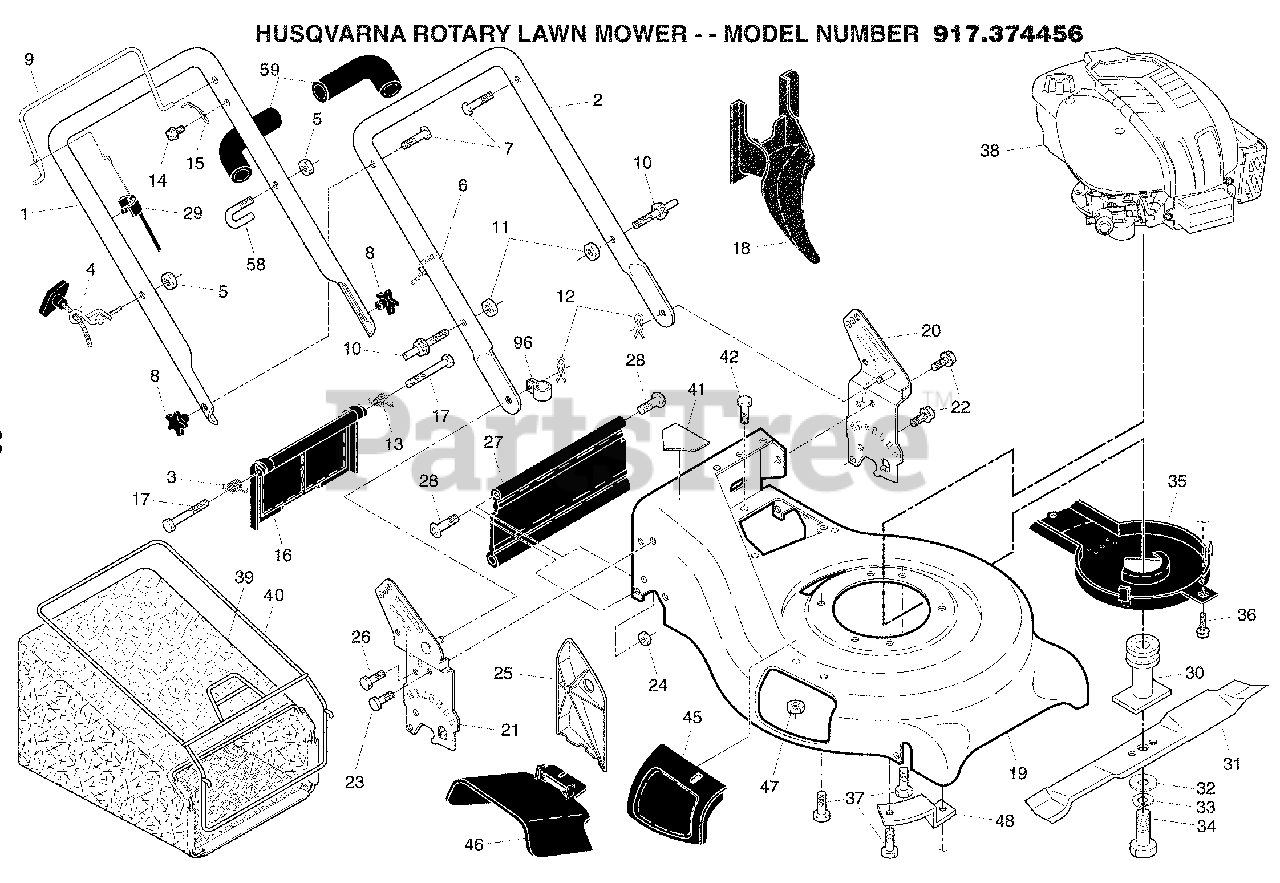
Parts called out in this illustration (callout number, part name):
1	Upper Handle Assembly
2	Handle, Lower
3	Spring, Rear Door, RH
4	Rope Guide
5	Nut, Hex, with Lockwasher Insert 1/4-20
6	Wire, Tie
7	Bolt, Handle 5/16-18 x 2-5/8
8	Knob, Handle
9	Control Bar
10	Pin, Handle Adjustment
11	Nut, Hex
12	Cotter, Hairpin
13	Spring, Rear Door, LH
14	Screw
15	Bracket, Upstop
16	Rear Door Assembly
17	Bolt, Rear Door
18	Plug, Mulcher
19	Kit, Housing
20	Handle Bracket Asembly, LH
21	Handle Bracket Assembly, RH
22	Screw, Hex Washer Head
23	Bolt, Hex Head 5/16-18 x 5/8
24	Nut, Hex, with Lockwasher Insert 5/16-18
25	Baffl e, Side
26	Screw, Hi-Lo Thread #12 x 5/8
27	Skirt, Rear
28	Screw, Hinge 1/4-20 x 1.25
29	Cable, Operator Presence
30	Blade Adapter / Pulley
31	Blade, 21"
32	Washer
33	Washer, Lock
34	Bolt, Hex Head
35	Debris Shield
36	Bolt
37	Bolt, Engine
39	Grassbag
40	Frame, Grassbag
41	Danger Decal
42	Screw
45	Mulcher Door Assembly
46	Discharge Guard
47	Nut, Hex
48	Mounting Bracket, Debris Shield
58	Clip, Packaging
59	Grip, Foam
96	Clip, Cable
